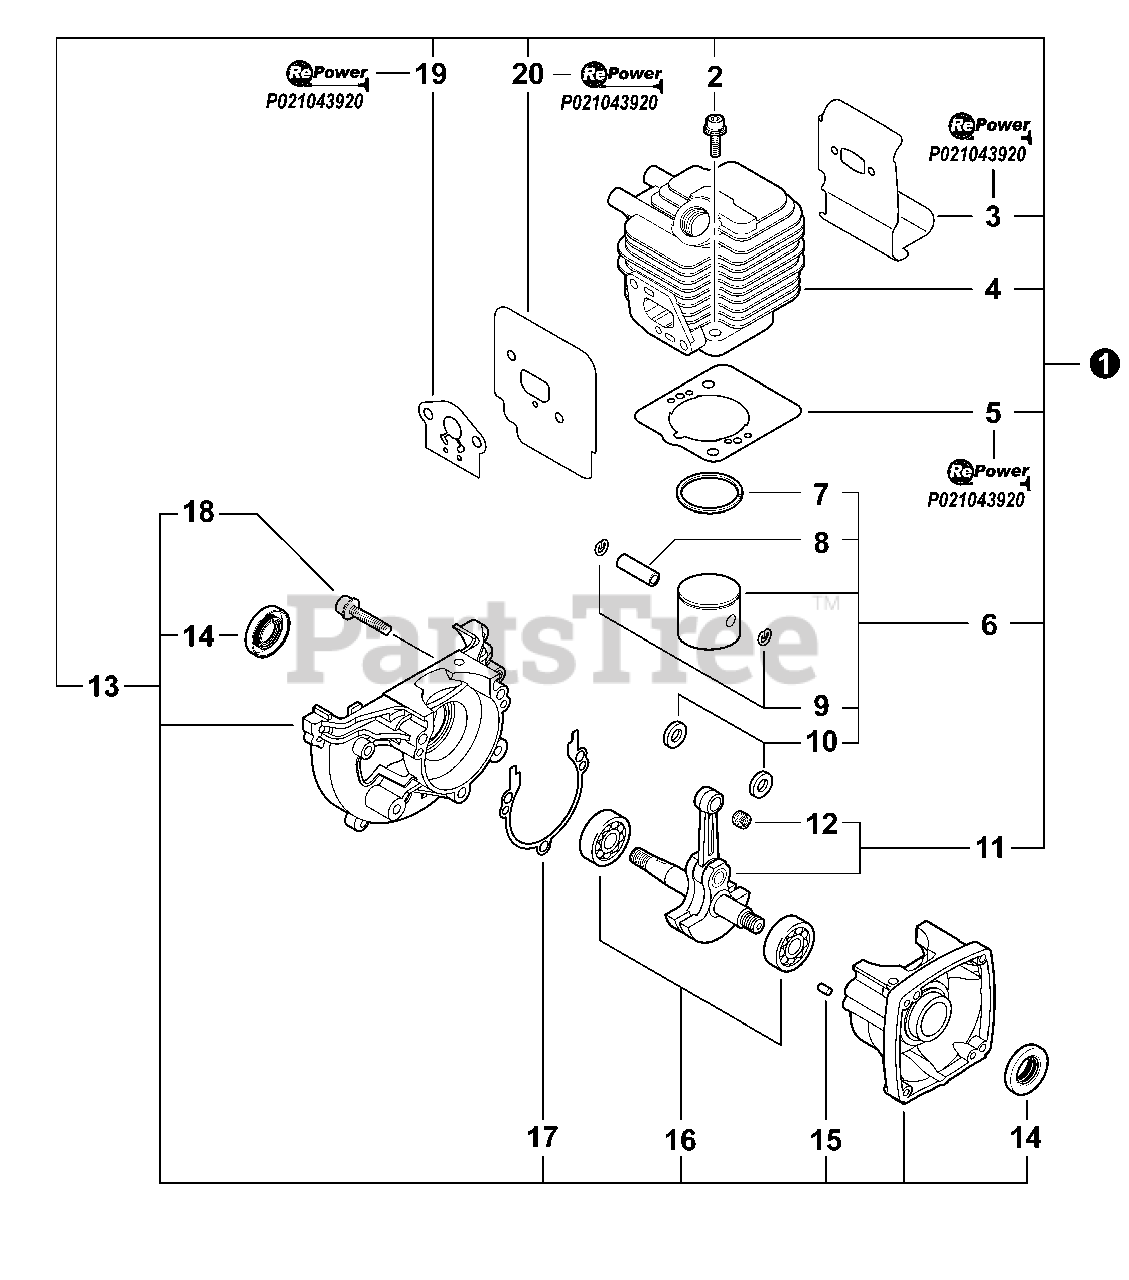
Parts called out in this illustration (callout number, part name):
1	SHORT BLOCK -- SB1107
2	SCREW - 5×22
3	SHIELD, EXHAUST
4	CYLINDER
5	GASKET, CYLINDER
6	PISTON KIT
7	RING, PISTON
8	PIN, PISTON
9	RING, RETAINING
10	SPACER, PISTON
11	CRANKSHAFT ASY
12	BEARING, NEEDLE - 8
13	CRANKCASE KIT
14	SEAL, OIL
15	PIN, DOWEL
16	BEARING, BALL - 6201
17	GASKET, CRANKCASE
18	SCREW - 5×28
19	GASKET, INTAKE
20	SHIELD, INTAKE
